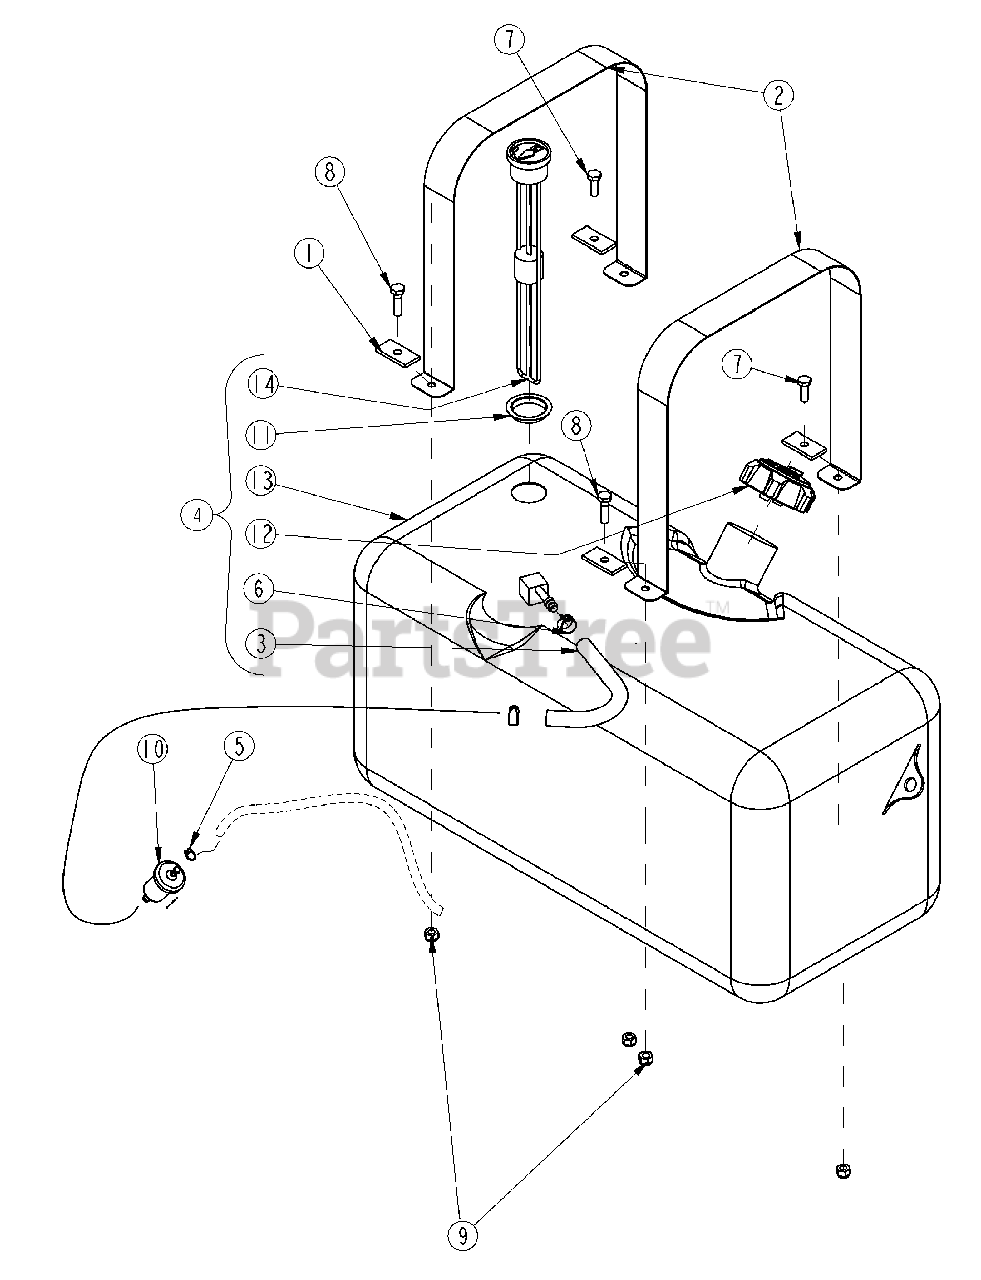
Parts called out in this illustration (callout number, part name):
1	GAS TANK MOUNT SPACER
2	GAS TANK STRAP, WIDE
3	FUEL LINE 9" ST MODEL
4	ST FUEL TANK ASSY
5	PINCH CLAMP HONDA .32OD HOSE
6	CLAMP PINCH FOR .50 OD HOSE
7	HHCS 1/4-20X3/4 GR5
8	HHCS 1/4-20X1 GR5
9	NUT HEX NYLOCK 1/4-20
10	HONDA FUEL FILTER
11	GROMMET FOR FUEL GAUGE
12	FUEL CAP TALL
13	FUEL TANK 8 GALLON ST
14	FUEL GAUGE
